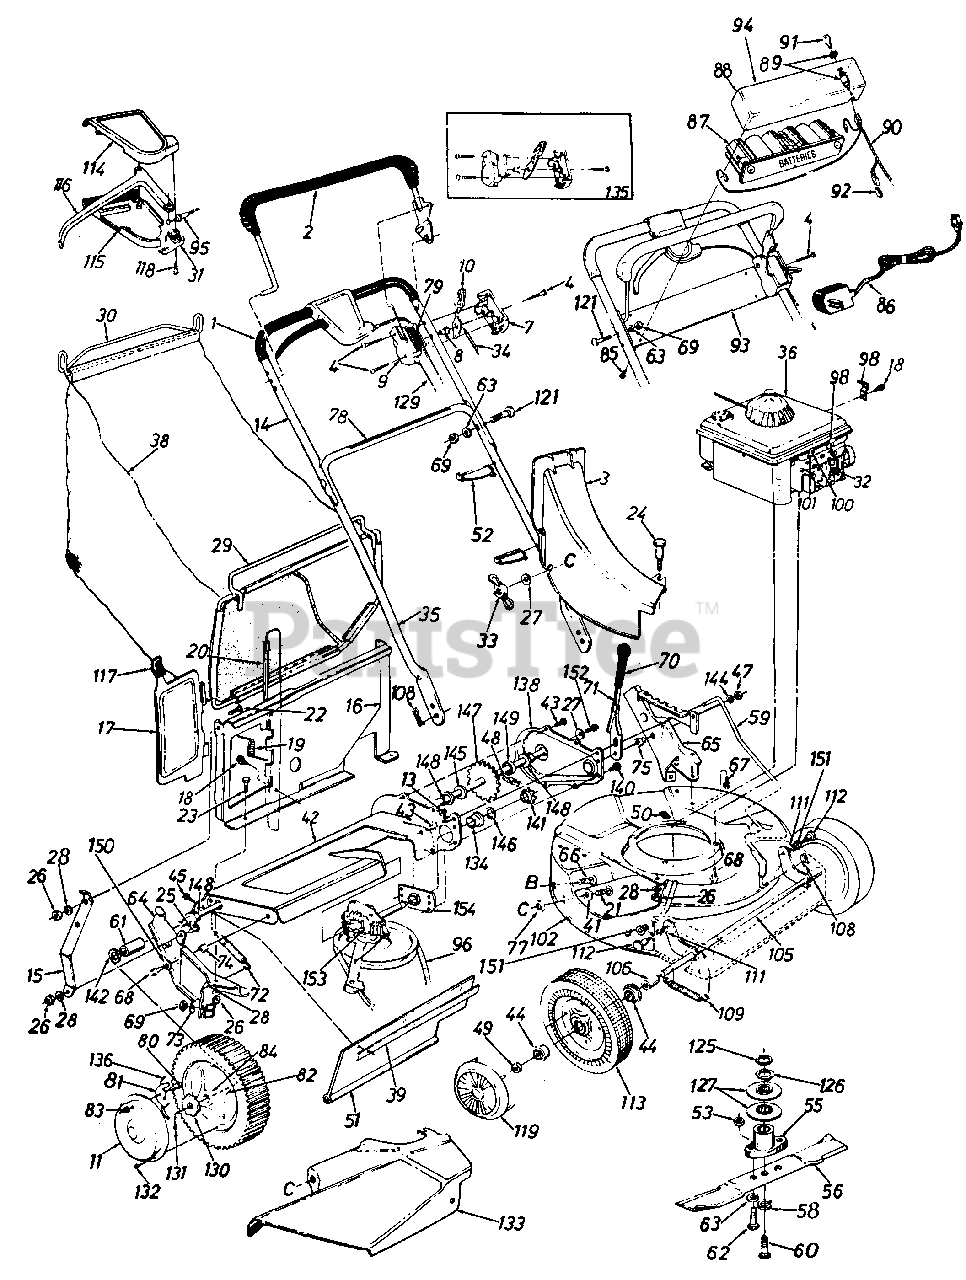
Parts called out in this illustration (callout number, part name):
1	GRIP-SHRINK-25 IN
3	CHUTE ASSY-TOP DISCH
4	SCREW-TRUSS MACH
7	PANEL HALF-CONTROL
8	PIN-CONTROL DISC
9	PANEL HALF-CLUTCH
10	LEVER-THROTTLE CONT-REV
11	HUB CAP
13	PIN-COTTER-3/32 DIA X .75
14	HANDLE-UPPER-CHROME
15	BRACKET-PANEL SUP
16	PANEL ASSY-CATCHER
17	DOOR-TOP DISCHARGE
18	SCREW-HEX B-TAP #10 X .38
19	SPRING-TORSION
21	BOLT-CARRIAGE 1/4-20 X .62
22	SCREW-TRUSS MACH
23	SCREW-HEX 1/4-20 X .50
24	SCREW-SHLD
25	SCREW-HEX 1/4-20 C .62
26	NUT-HEX 1/4-20
27	WASHER-SPRING BELL
28	LOCK WASHER 1/4 DIA
29	FRAME-FRONT
30	HANDLE-GRASSCATCHER
31	CAP-CABLE MTG
32	INSULATOR-SPARK PLUG
33	NUT-INS WING L-1/4-20
34	WIRE-THROTTLE 58 LG
35	HANDLE-LOWER PAINTED
38	BAG-GRASS-CONV
39	STRIP-RETAINING
41	WASHER-FL-.344 ID X .62 OD X .033
42	AXLE ASSY-CHAIN
43	SCREW-HEX B-TAP 1/4 X .38
44	BEARING-BALL
45	SCREW-HEX WASH HD
47	NUT-HEX LOCK 3/8-24
48	#48 CHAIN 1/2 PITCH
49	NUT-HEX INS L-1/2-20
51	FLAP-RR
52	TIE-CABLE
53	NUT-5/16-24
55	ADAPTER-BLADE
56	BLADE-21IN
58	WASHER-BELL BLADE
59	ROD-HGT ADJ 1.50 X 19.42
60	SCREW-HEX 7/16-20 X 1.50
61	SPACER-.513 ID X .703 OD X .69
62	SCREW-HEX SPECIAL 5/16-24X1.0
63	WASHER-LOCK-5/16
64	BRACKET ASSY-HDLE-RH
65	BRACKET ASSY-HDLE-LH
66	BOLT-CARRIAGE 5/16-18 X .62
67	SCREW-HEX WASH HD 5/16-18X1/2
68	SCREW-HEX R
69	NUT-HEX 5/16-18
71	LEVER-HGT ADJ
72	SPRING-EXTENSION
73	WASHER-BELL .337 X .867 X .057
75	SPACER-SHLD .500 X .100
77	RETAINER-BOLT 1/4X.50 OD
80	SCREW-SHLD .342 DIA X .268
81	PAWL
82	WHEEL ASSY W/TIRE-T-TREAD
83	NUT-INS LOCK 1/4-20
84	BEARING-BALL
85	SCREW-TAP .215 X 1
86	CHARGER-BATTERY
87	BATTERY PACK
88	TRAY-BATTERY-UPPER
89	SWITCH-KEY
90	WIRE HARNESS
91	KEY-IGN (SET OF TWO)
92	PLUG
93	TRAY-BATTERY-LOWER
94	STARTING LABEL
95	CABLE-CLUTCH X 50.0
96	BELT-V 3/8 X 31.0
98	CLAMP-CASING
100	SCREW-HEX WASH HD TAP
101	CLAMP-CASING
108	PIN-INTERN COT-5/16 DIA
109	SPRING-EXTENSION
111	WASHER-INTERN L 3/8 X.56 OD X .018
112	SCREW-SHLD
113	WHEEL ASSY W/TIRE
114	COVER-HALF-CONTROL
115	COVER-HALF CONT-LWR
116	LEVER-CONTROL
118	SCREW-FL C-SUNK AB
119	HUB CAP-BLACK
121	BOLT-CARRIAGE-CURV 5/16-18 X 1.38
125	WASHER-SERRATED
126	WASHER-WAVE
127	PULLEY HALF-SERRATED
129	CABLE-CONTROL
130	RATCHET
131	PIN-COTTER-1/8 DIA X 1.00
132	SCREW-PAN HD TAPP
133	DEFLECTOR ASSY
134	BUSHING-FL
135	KIT-THROTTLE CONTROL
136	SPRING-NYLON
138	COVER-CHAIN
140	SCREW-HEX WASH SF TAPP
141	SPROCKET-7T
142	WASHER-FL
144	WASHER-FL-.385 ID X .87 OD X .06
145	WASHER-FL
146	WASHER-FL
147	SHAFT ASSY-REAR
148	BEARING-HEX FLANGE .506 ID
149	WASHER-FL-.531 X .930 OD X .050
150	WASHER-FL-.531 ID X 1.25 OD X 1.00
151	BEARING-NYLINER
152	SCREW-1/4-20 X .62
153	TRANSMISSION-COMP
154	BEARING-CUP HEX
